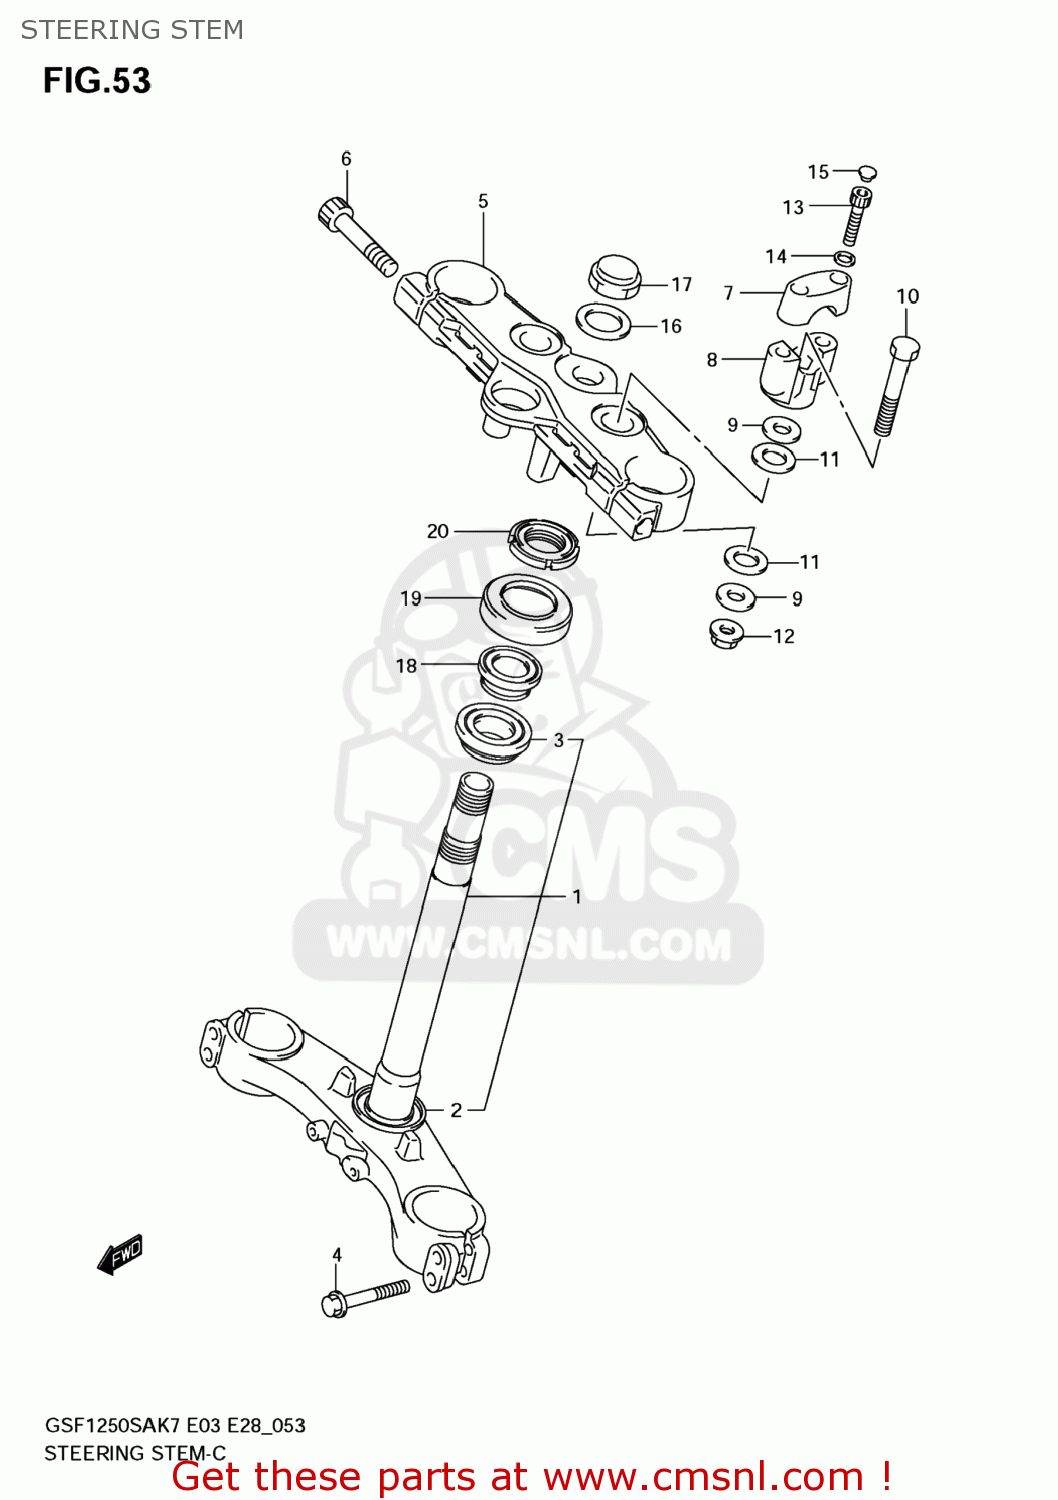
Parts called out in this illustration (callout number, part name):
1	STEM,STEERING
2	SEAL,STEERING LWR
3	BEARING(30X55X17)
4	BOLT(8X40)
5	HEAD,STEERING STEM
6	BOLT
7	HOLDER,HANDLE
8	HOLDER,HANDLE UNDER
9	WASHER
10	BOLT
11	RUBBER SEAT
12	NUT
13	BOLT,HANDLE HOLDER
14	WASHER
15	CAP(OD:11)
16	WASHER
17	NUT,CAP
18	BEARING(25X47X15)
19	DUST SEAL,STEERING UPR
20	NUT,STEERING STEM
